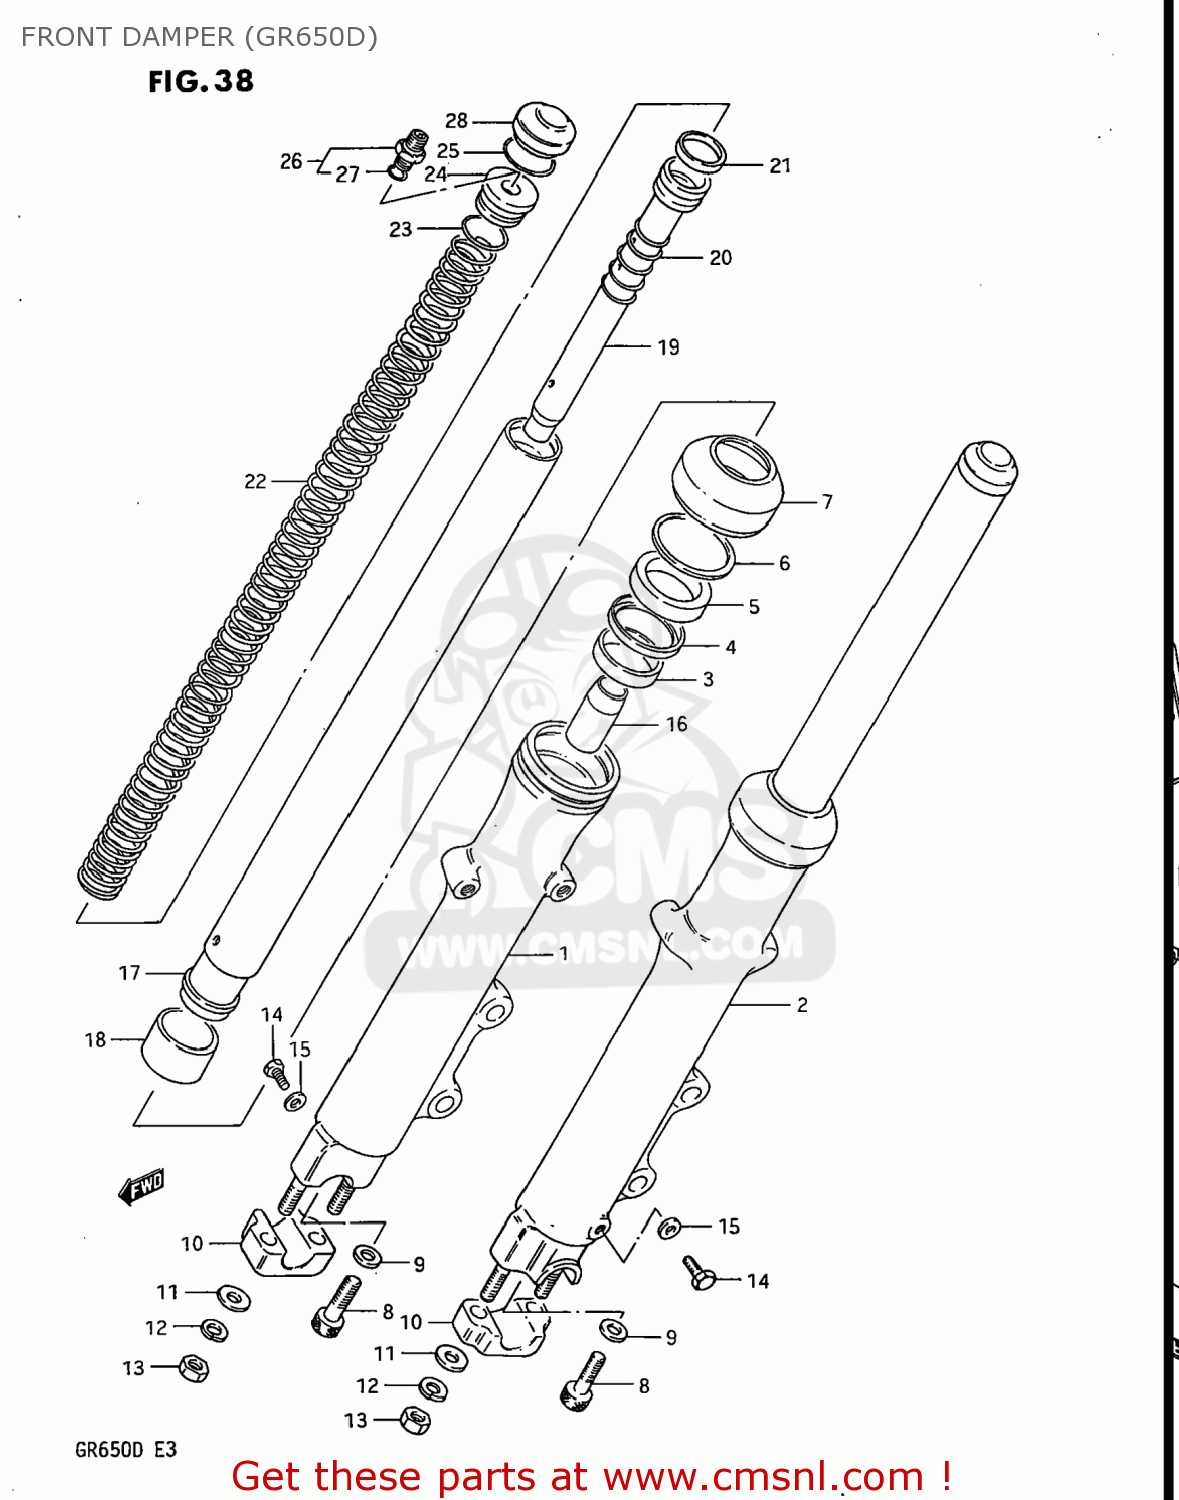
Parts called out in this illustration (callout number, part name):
1	TUBE,OUTER,RIGHT
2	TUBE,OUTER,LEFT
3	BUSHING,GUIDE
4	SPACER,SEAL
5	OIL SEAL,FRONT FORK
6	CIRCLIP,FORK OIL SEAL
7	BOOT
8	BOLT(8X27)
9	GASKET (NAS)
10	HOLDER,AXLE
11	WASHER
12	LOCK WASHER
13	NUT (8MM)
14	BOLT
15	GASKET,DRAIN,PLUG (NAS)
16	PIECE,OIL LOCK
17	TUBE,INNER
18	PISTON
19	CYLINDER
20	SPRING,REBOUND
21	RING,FRONT FORK PISTON
22	SPRING
23	O-RING
24	SEAT,SPRING
25	RING,STOPPER
26	VALVE,AIR
27	O-RING
28	CAP
